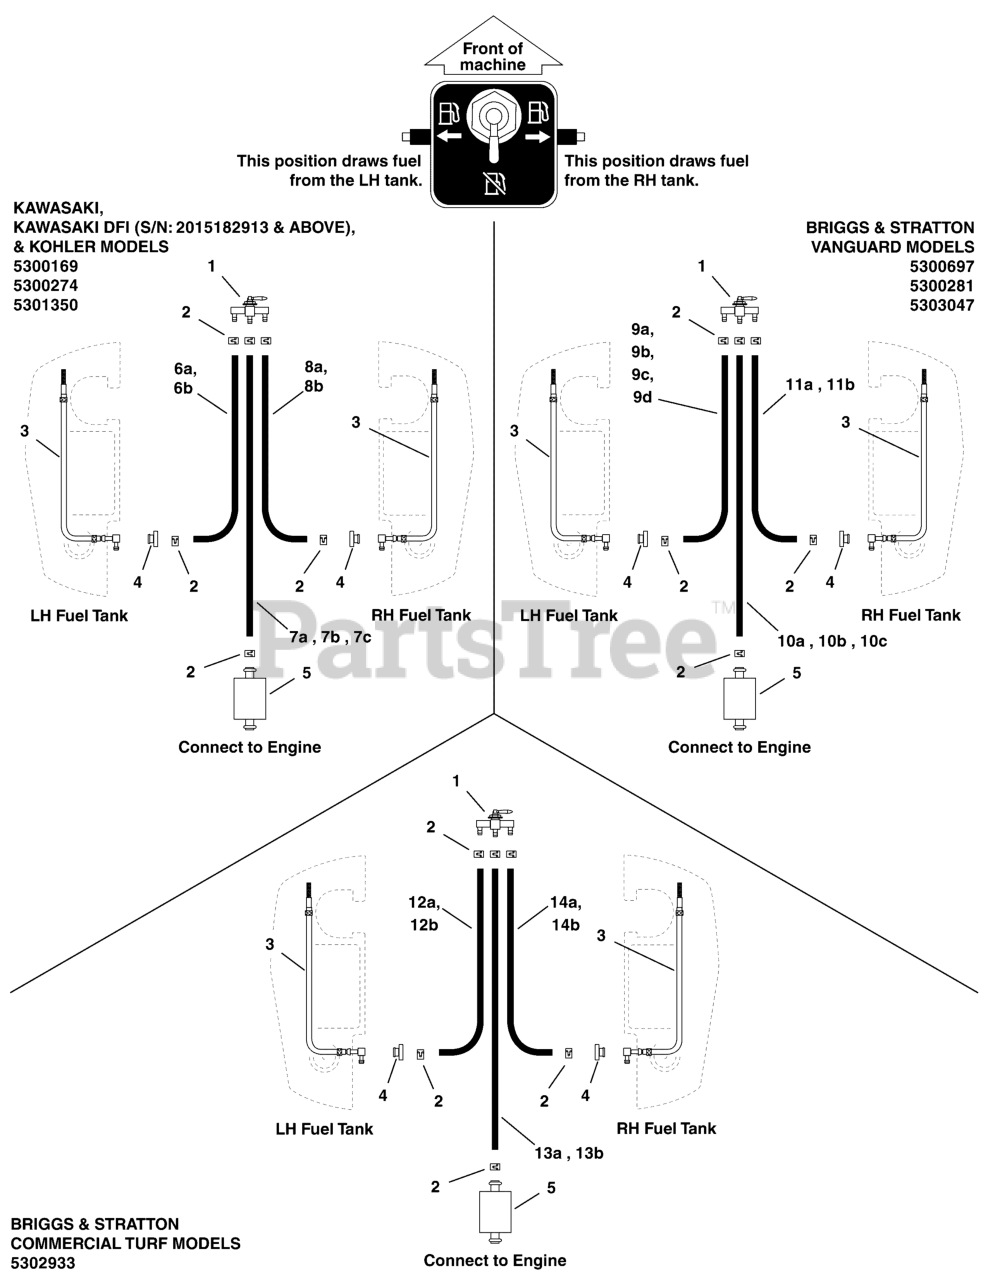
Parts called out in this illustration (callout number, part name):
1	VALVE, FUEL, STR. OUTLET
2	CLAMP, HOSE, EXTERNAL, 1/2 - RED
3	HOSE ASSEMBLY (DRAW TUBE)
4	BUSHING-FUEL TANK RED RUBBER
5	FUEL FILTER (SV)
